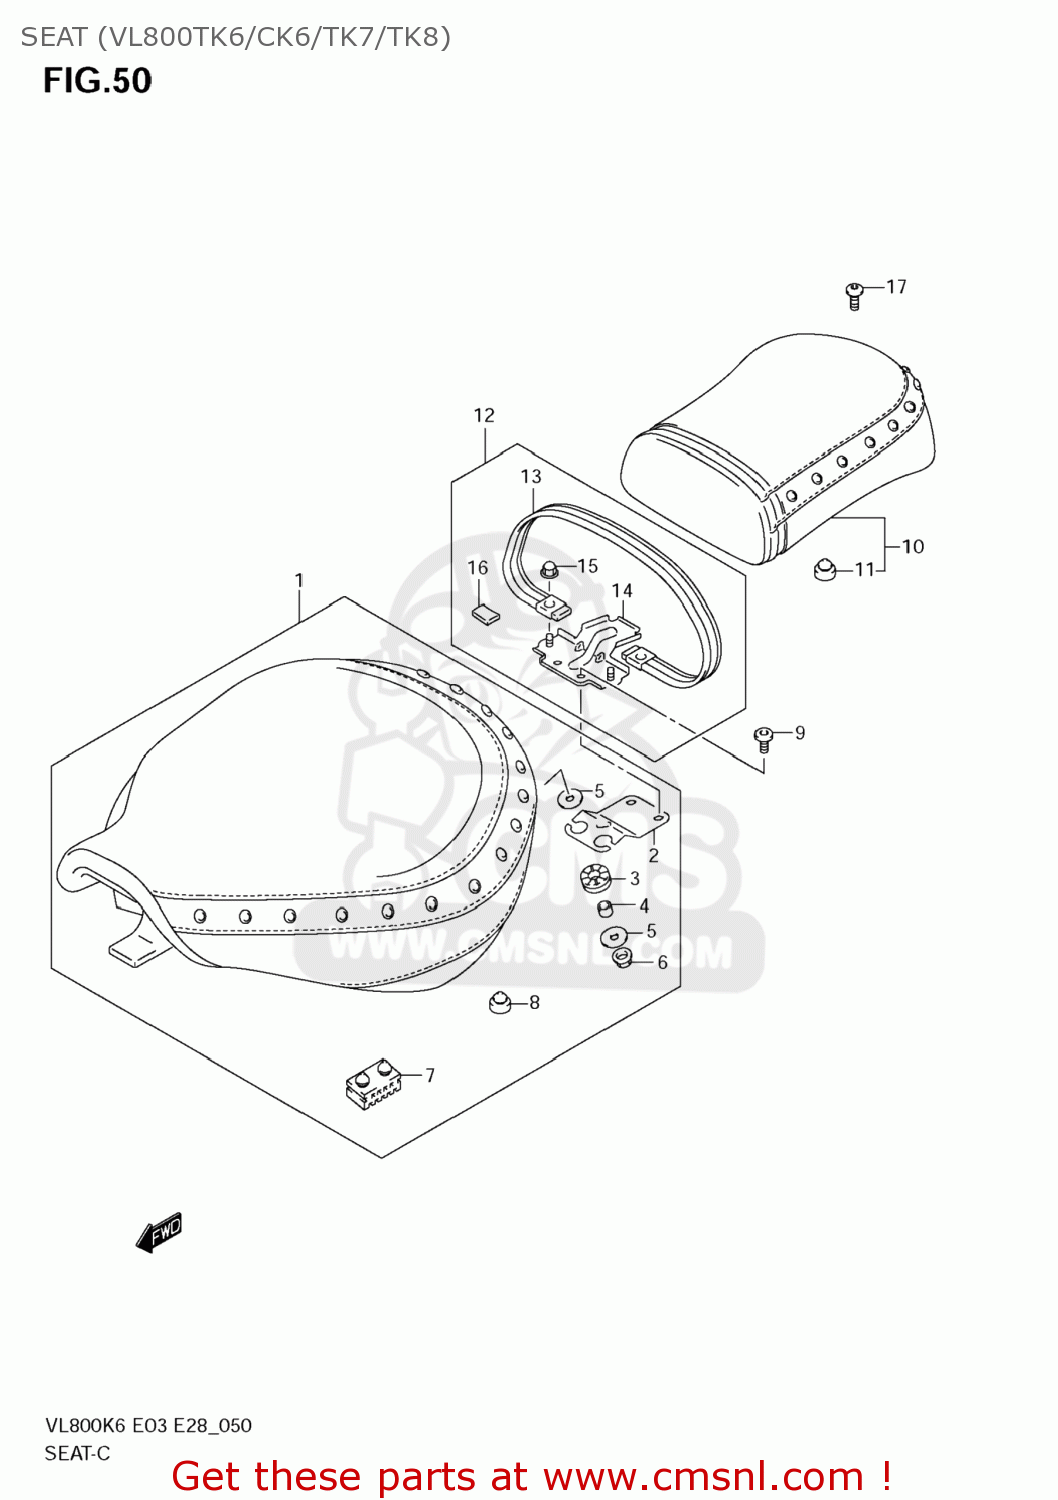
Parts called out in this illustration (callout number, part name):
1	SEAT ASSY(BLACK)
2	BRACKET,SEAT
3	CUSHION
4	SPACER(6.5X10.5X12)
5	WASHER(6.5X24X1.6)
6	NUT
7	CUSHION,SEAT(40X20X15)
8	CUSHION(11.5X22X20)
9	BOLT(6X18)
10	SEAT ASSY,PILLION
11	CUSHION(11.5X22X20)
12	BAND ASSY,SEAT(BLACK)
13	BAND,SEAT
14	BRACKET,SEAT BAND
15	NUT
16	PAD
17	BOLT(8X16)
